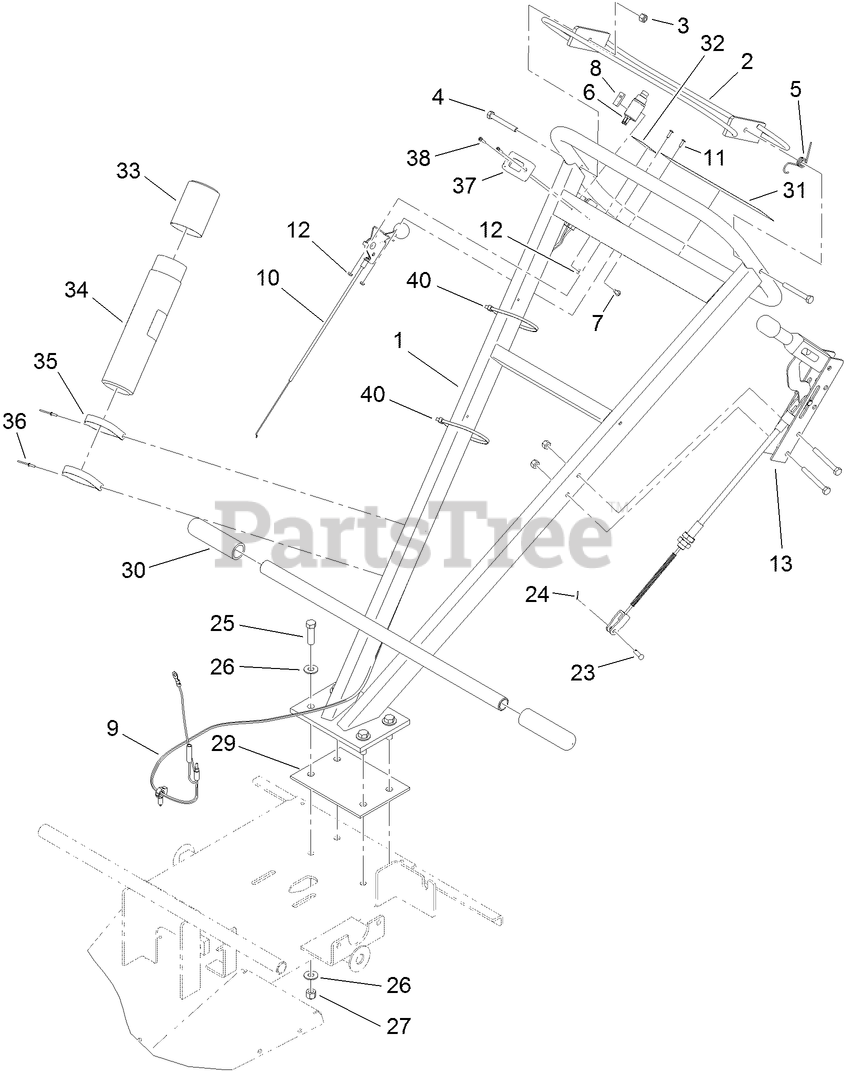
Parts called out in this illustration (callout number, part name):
1	OPERATOR HANDLE ASM
2	HANDLE-SAFETY
3	NUT-LOCK, NI
4	SCREW-HH
5	SPRING-RETURN
6	SWITCH-PLUNGER, NC (W/COVER)
8	PLATE-TAPPED
9	HARNESS-WIRE
10	CABLE-THROTTLE
11	SCREW-PRH
12	NUT-HEX
13	BRAKE LEVER ASM
23	PIN-CLEVIS
24	PIN-COTTER
25	SCREW-HH
26	WASHER-FLAT
27	NUT-LOCK, NI
29	GASKET-HANDLE
30	GRIP-HANDLE
31	DECAL-WARNING
32	DECAL-ENGAGE
33	CAP-HOUSING
34	TUBE-MANUAL
35	CLAMP-R
36	RIVET-POP
37	HOURMETER-INDUCTIVE
38	SCREW-PPH
40	TIE-CABLE
